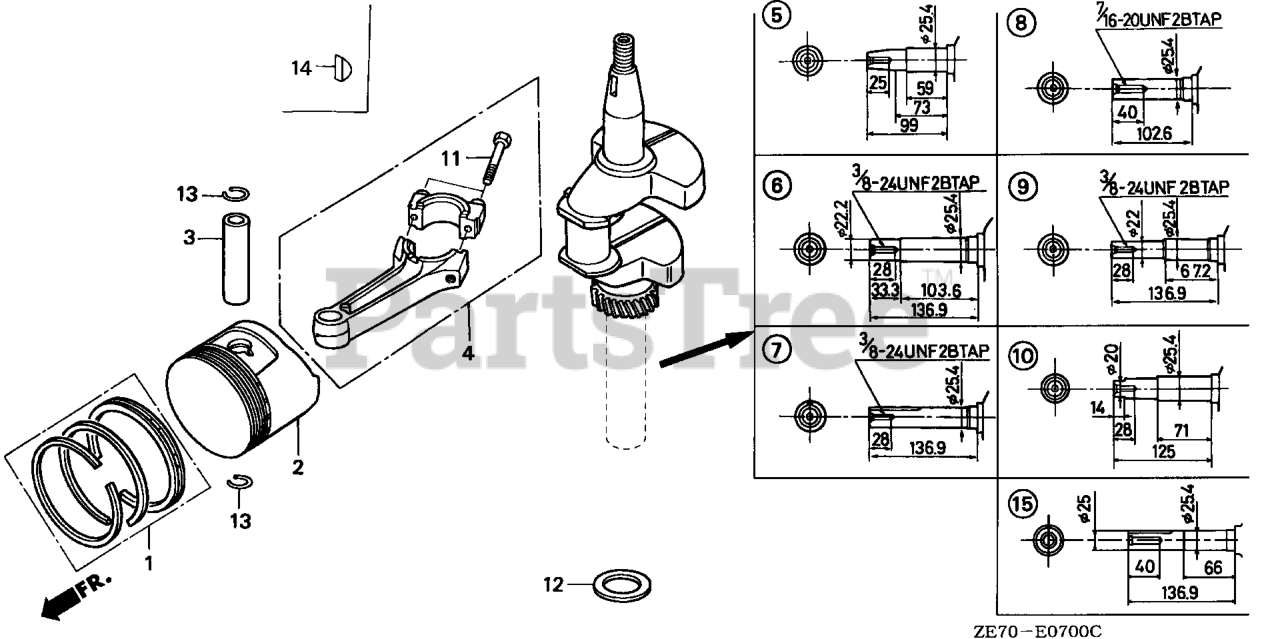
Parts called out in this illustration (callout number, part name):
1	RING SET, PISTON (STD) (TEIKOKU)
1	RING SET, PISTON (STD.) (NIPPON)
1	RING SET, PISTON (OS 0.25) Use from Engine SN 7603339.
1	RING SET, PISTON (0.25) (NIPPON) Use up to Engine SN 1314912.
1	RING SET, PISTON (OS 0.50) Use from Engine SN 7603339.
1	RING SET, PISTON (0.50) (NIPPON) Use up to Engine SN 1314912.
1	RING SET, PISTON (0.75) (TEIKOKU) Use up to Engine SN 1314912.
1	RING SET, PISTON (0.75) (NIPPON) Use up to Engine SN 1314912.
2	PISTON (0.25)
2	PISTON (0.75)
2	PISTON (STD)
2	PISTON (OS 0.50)
3	PIN, PISTON
4	ROD ASSY., CONNECTING (0.25 LOWER SIZE) (NOT AVAILABLE)
4	ROD ASSY., CONNECTING (IDENT MARK Z)
11	BOLT, CONNECTING ROD
12	WASHER, THRUST (25.6MM)
13	CLIP, PISTON PIN (18MM)
15	CRANKSHAFT
